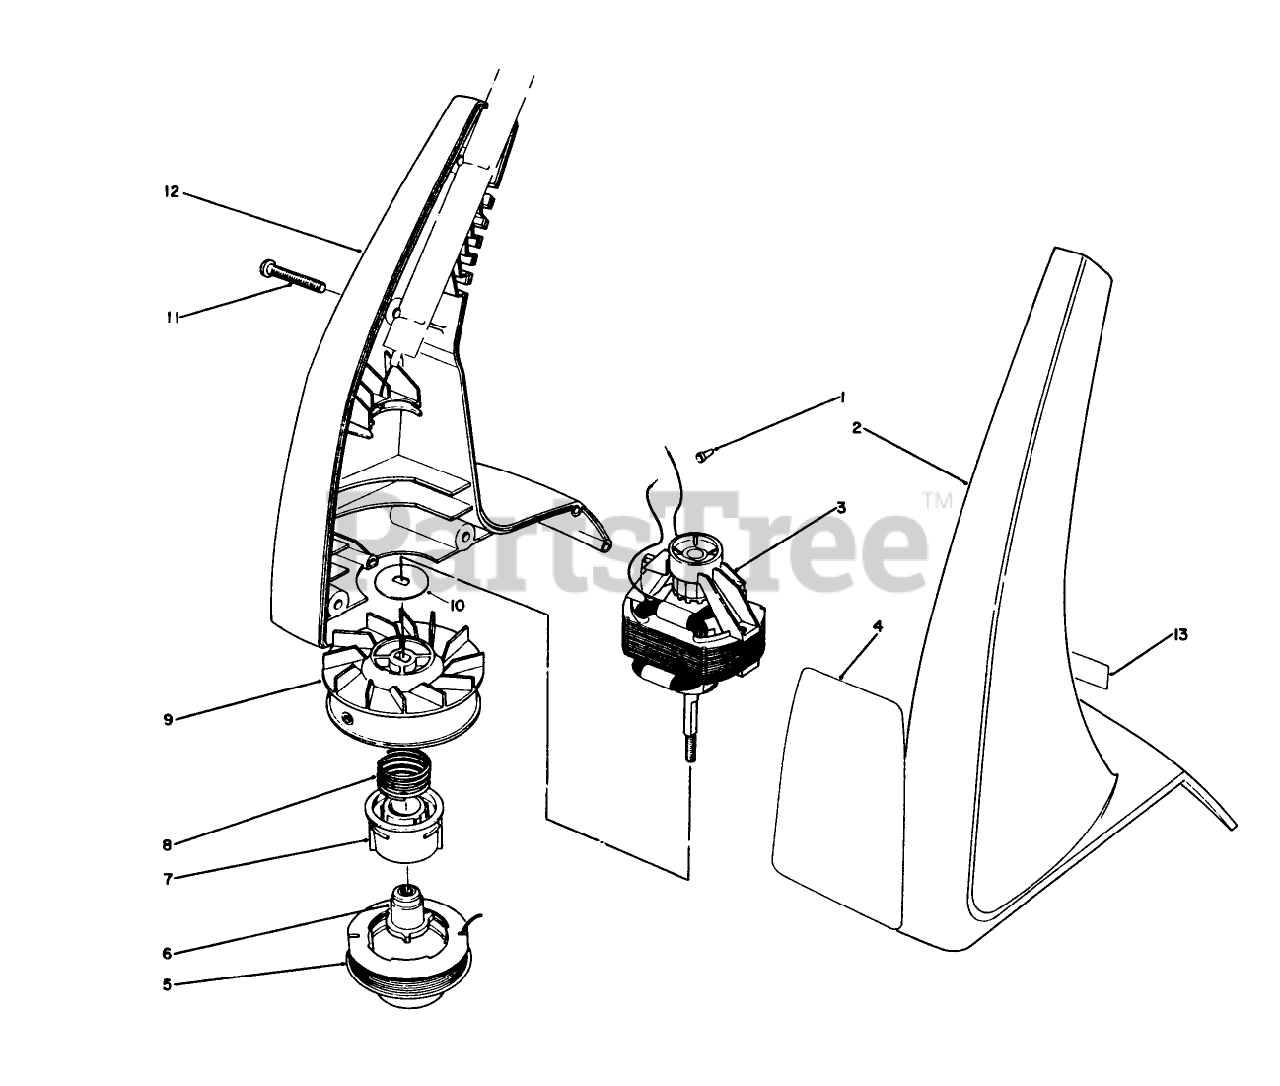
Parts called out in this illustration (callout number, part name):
1	CONNECTOR WIRE JOINT
2	L.H. HOUSING, 910
3	MOTOR, 910 TRIMMER
4	DECAL, 8" TRIMMER
5	Cutting Line (12- .05 Dia.)
6	DRIVER
7	CORE - SPOOL
8	Spring
9	Drum w/Eyelet
10	MOTOR WASHER
11	Screw
12	Housing-R.H.
13	Decal
